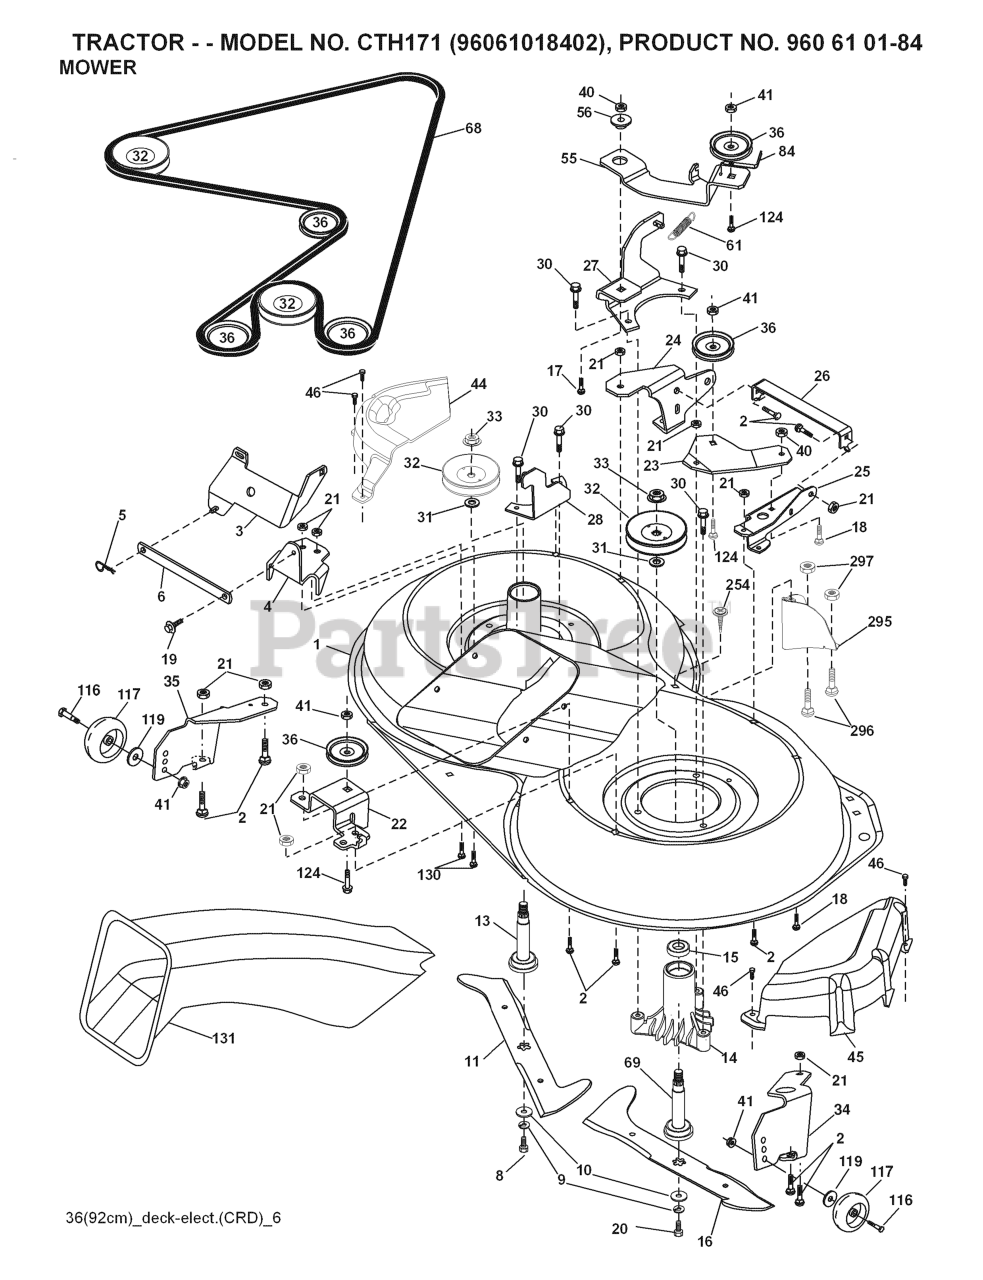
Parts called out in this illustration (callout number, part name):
2	RP BOLT 5/16-18 X3/4 ZN/YEL GR
5	RETAINER-SPRNG RB
6	BAR.SWAY.92.CRD
8	BOLT.3/8-24X1.25 GR8
9	LOCKWASHER
10	WASHER.BLADE
13	SHAFT ASM VENT
14	HOUSING.MANDREL.VENTED (MACHD)
17	BOLT.3/8-14X1.25
19	BOLT SHD 5/16-18
20	BOLT.3/8-24X1.25GR8. LHTHRD
21	LOCKNUT
26	SUPPORT
30	SCREW, WASHER HEAD
31	WASHER.SPACER.MANDREL
32	PULLEY MANDREL
33	NUT.FLANGE.LOCK.TOP
36	PULLEY.IDLER.4.25
41	NUT LOCK FLG 3/8-16 UNC
45	COVER.MANDREL.RH.CRD
46	SCREW.1/4-20X5/8
55	ARM.IDLER.92 CRD.2006
56	SPACER.RETAINER.MOWER
61	SPRING
68	BELT.DRIVE.92CM.CRD.2006
69	SHAFT.ASM.W/LWR.BRG.RH.THREAD
84	KEEPER, BELT IDLER
116	BOLT.SHOULDER.3/8-16X3-5/8.
117	RP WHEEL. GUAGE RALLY
118	NUT LOCK FLG 3/8-16 UNC
119	WASHER
124	BOLT.3/8-16X1.50
130	BOLT.CARR.SQNK.5/16-18UNC.X3/4
131	CHUTE BAGGER
254	SCREW 3/8-16X1
296	BOLT
297	NUT CENTERLOCK
